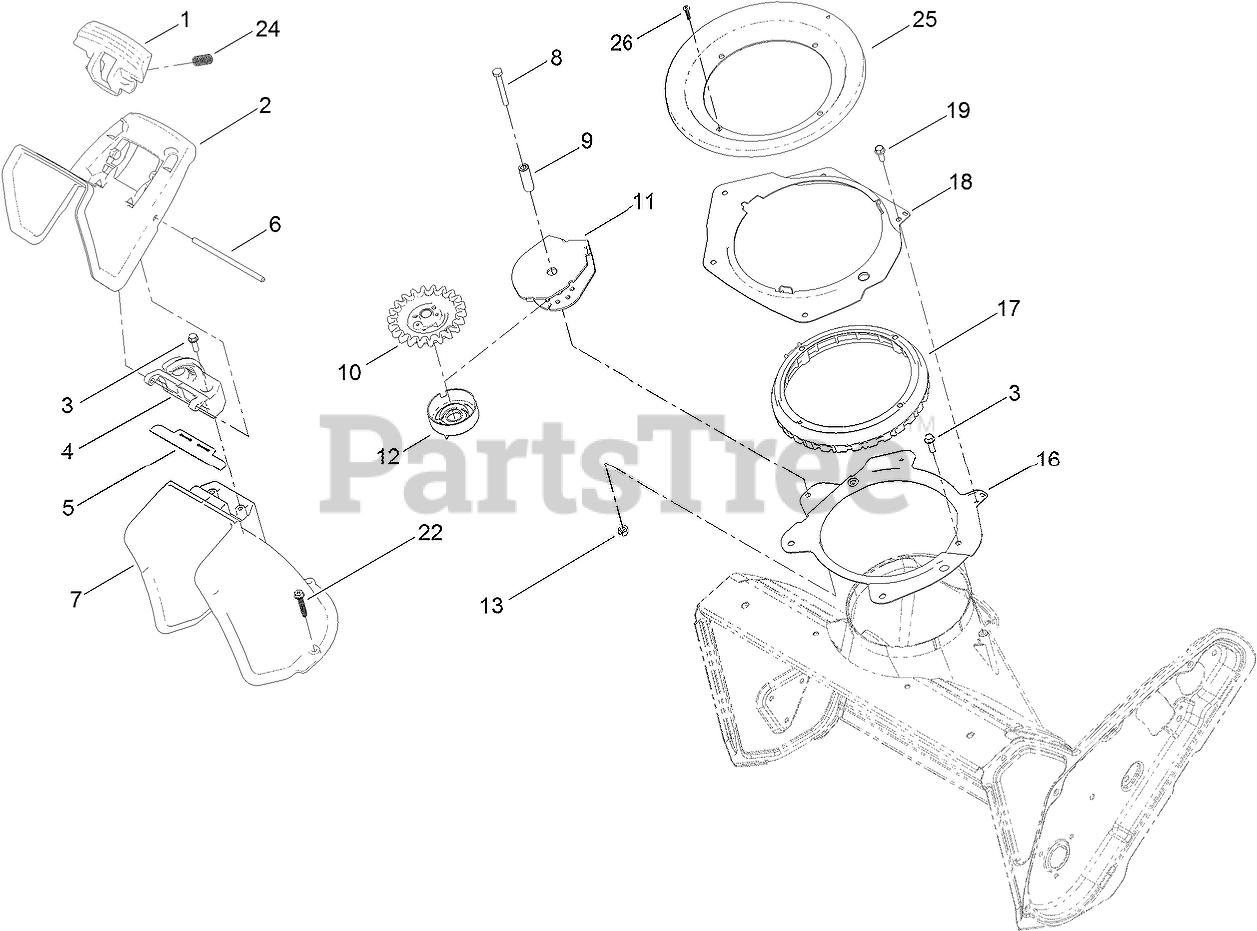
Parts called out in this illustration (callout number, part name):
1	TRIGGER-DEFLECTOR
2	DEFLECTOR-CHUTE, CE
3	SCREW-HWH
4	HINGE-RATCHET, DEFLECTOR
5	SEAL-DEFLECTOR
6	PIN-HINGE, DEFLECTOR
8	SCREW-HH
9	SPACER-SLEEVE, PINION
10	PINION-GEAR
11	BRACKET-PINION
12	RETAINER-CABLE
13	NUT-LOCK, NI
16	RING-SUPPORT, CHUTE
17	RING-CHUTE, GEAR
18	RETAINER-RING, CHUTE
19	SCREW-HWH
22	SCREW-PLASTITE
24	SPRING-COMPRESSION
25	SEAL-RING, CHUTE
26	SCREW-PPH
